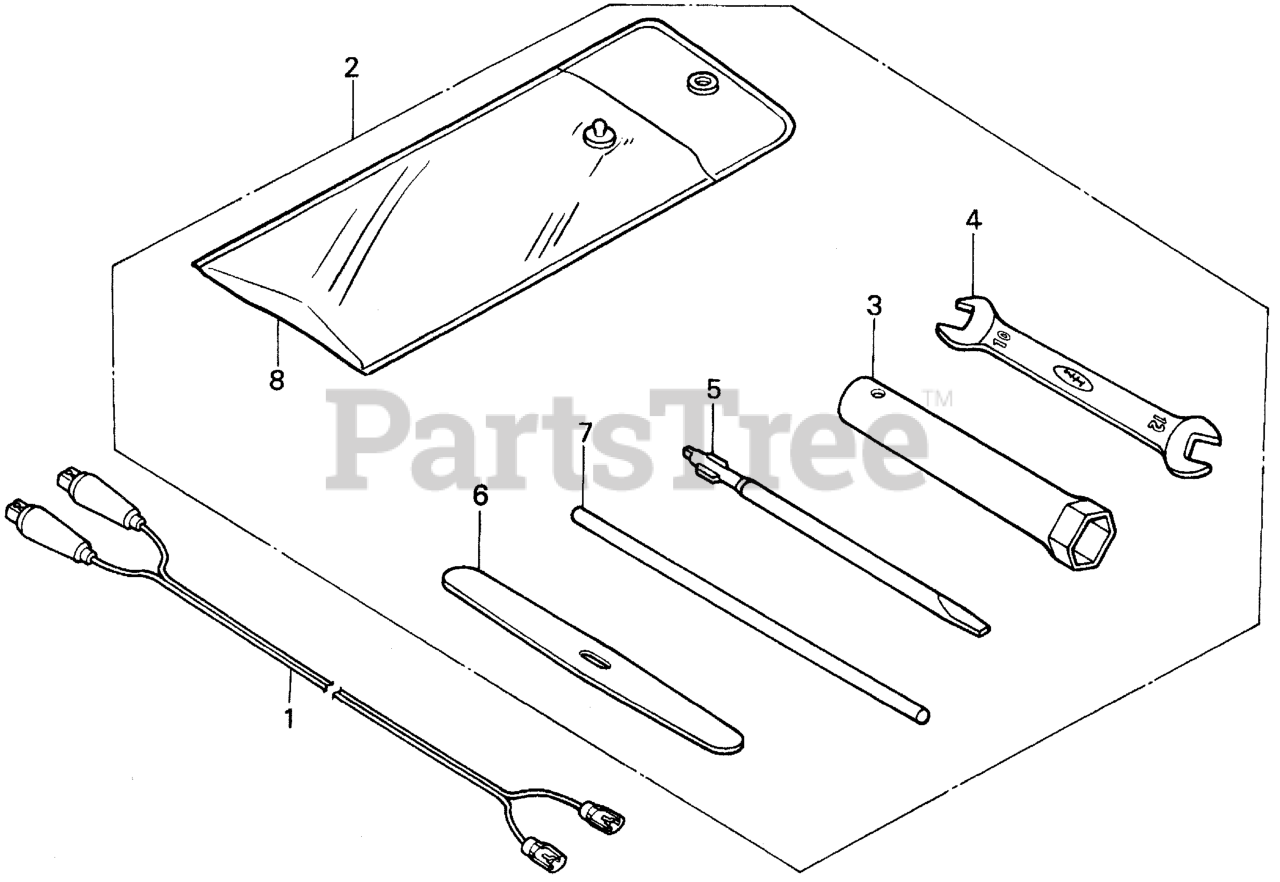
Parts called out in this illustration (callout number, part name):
2	TOOL KIT (NOT AVAILABLE)
3	WRENCH, BOX (P21)
4	WRENCH (10X12) (OPEN END)
5	SCREWDRIVER 3, STRAIGHT SLOT (NO. 2)
6	LEVER, TIRE
7	BAR A, HANDLE
8	BAG, TOOL
